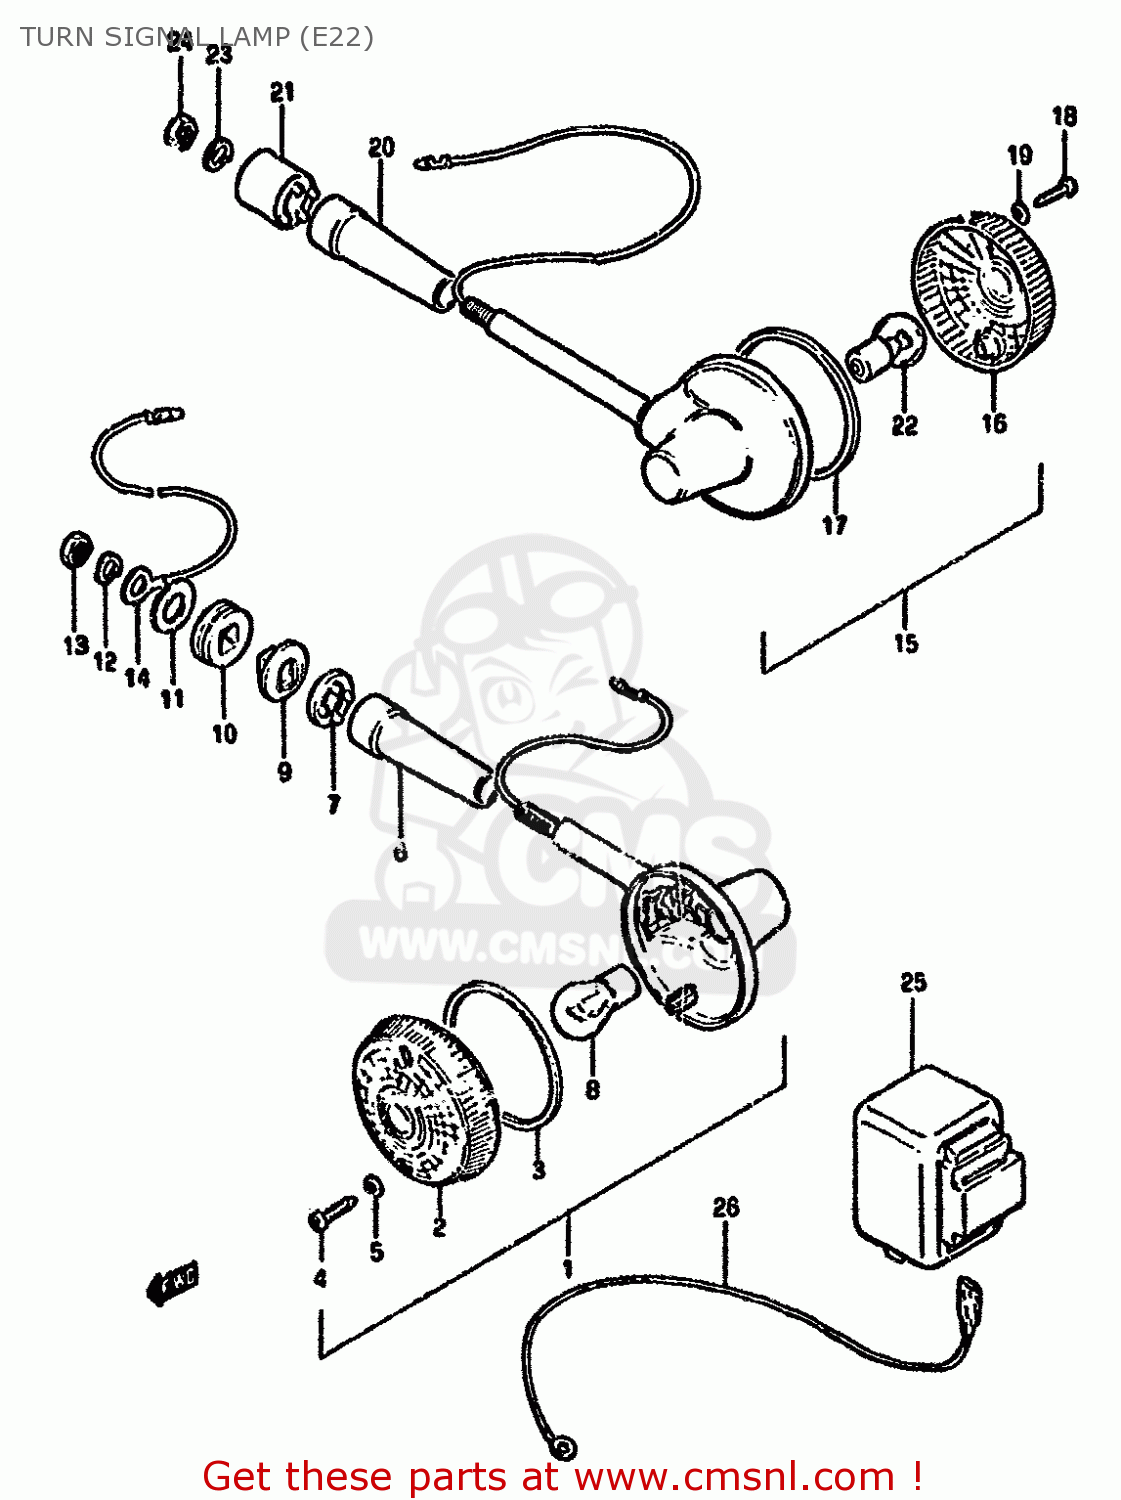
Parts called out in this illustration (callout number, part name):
1	LAMP ASSY,FR TURN SIGNAL
2	LENS
3	GASKET (NAS)
4	SCREW
5	GASKET (NAS)
6	COVER,STAY
7	CUSHION
8	BULB(12V21W)
9	SPACER
10	CUSHION
11	WASHER (10.5X30X2.3)
12	WASHER,LOCK
13	NUT
14	LEAD WIRE,EARTH
15	LAMP ASSY,RR TURNSIGNAL
16	LENS,TURN SIGN
17	GASKET (NAS)
18	SCREW
19	GASKET (NAS)
20	COVER,STAY
21	CUSHION
22	BULB(12V21W)
23	WASHER,LOCK
24	NUT
25	RELAY ASSY,TUR
26	LEAD WIRE
